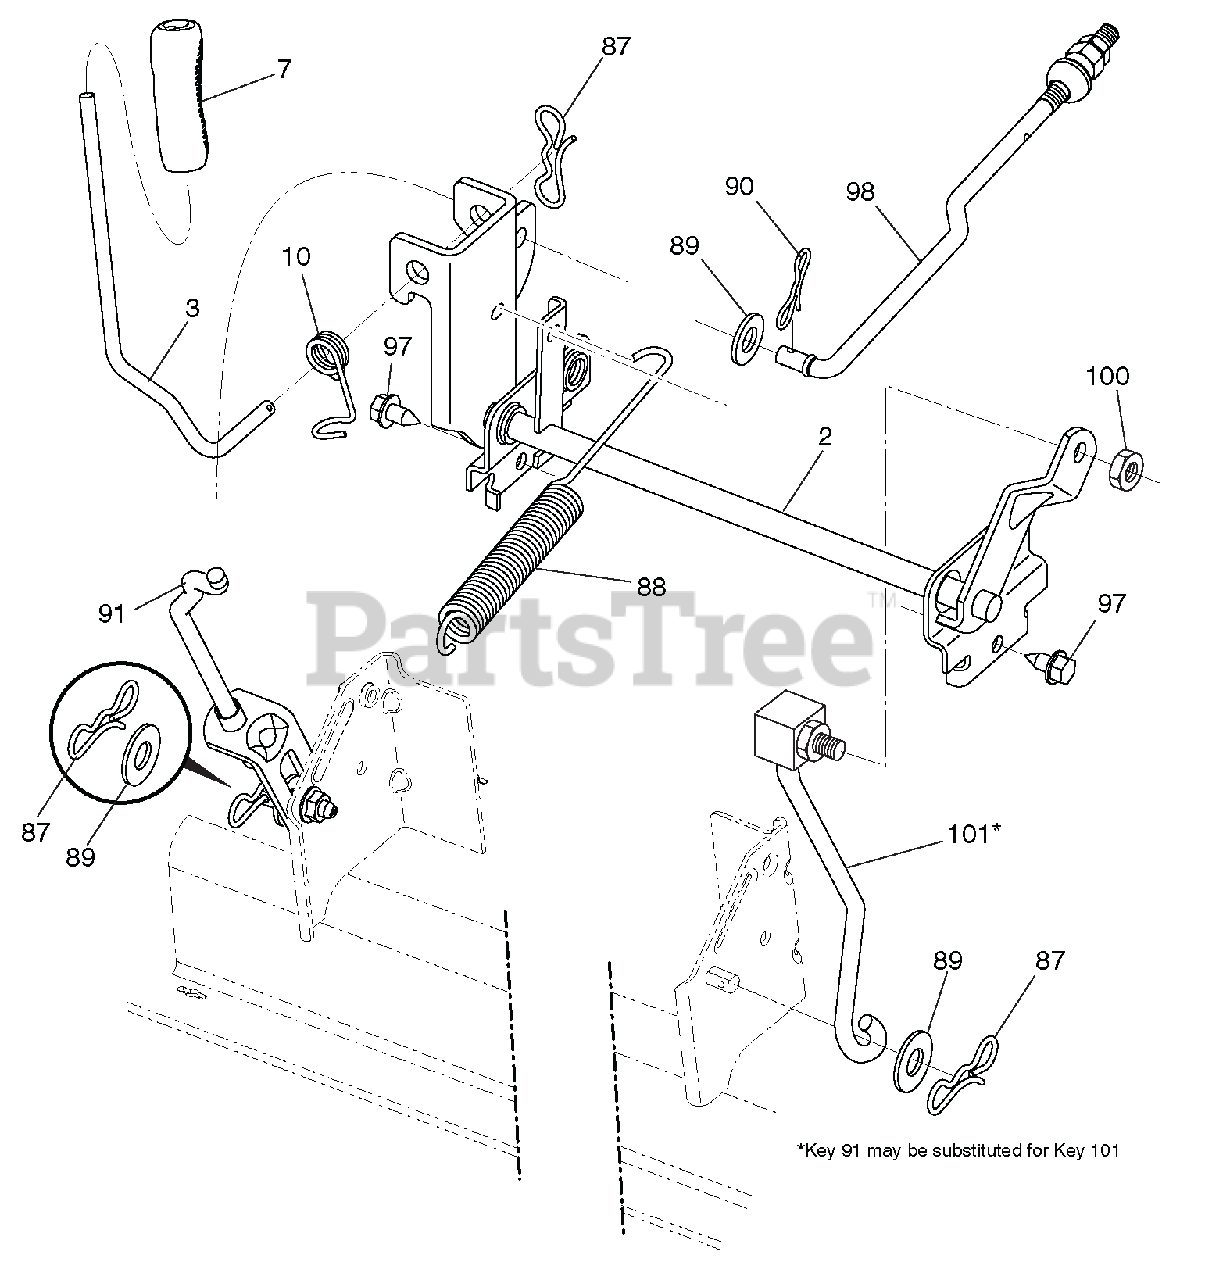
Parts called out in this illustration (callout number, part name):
2	SHAFT ASM., LIFT
3	LEVER.LIFT.HANDLE.LT
7	GRIP LEVER 5625 LD BLACK 428
10	SPRING.TORSION.HANDLE.LIFT
87	PIN.COTTER.7/16.BOW TIE LOCK
88	SPRING.LIFT ASSIST
89	WASHER.CLEAR ZINC
90	PIN.COTTER.5/16.BOW TIE LOCK
91	LINK ASM.LIFT.LH.REAR
97	SCREW.HEXWSH THDR3/8-16X3/4.BL
98	LINK ASM.SUSP.FRONT.MWR.11
100	NUT.CENTERLOCK.3/8-16 UNC.
101	LINK ASM.LIFT.FIXED.38/42/46"
